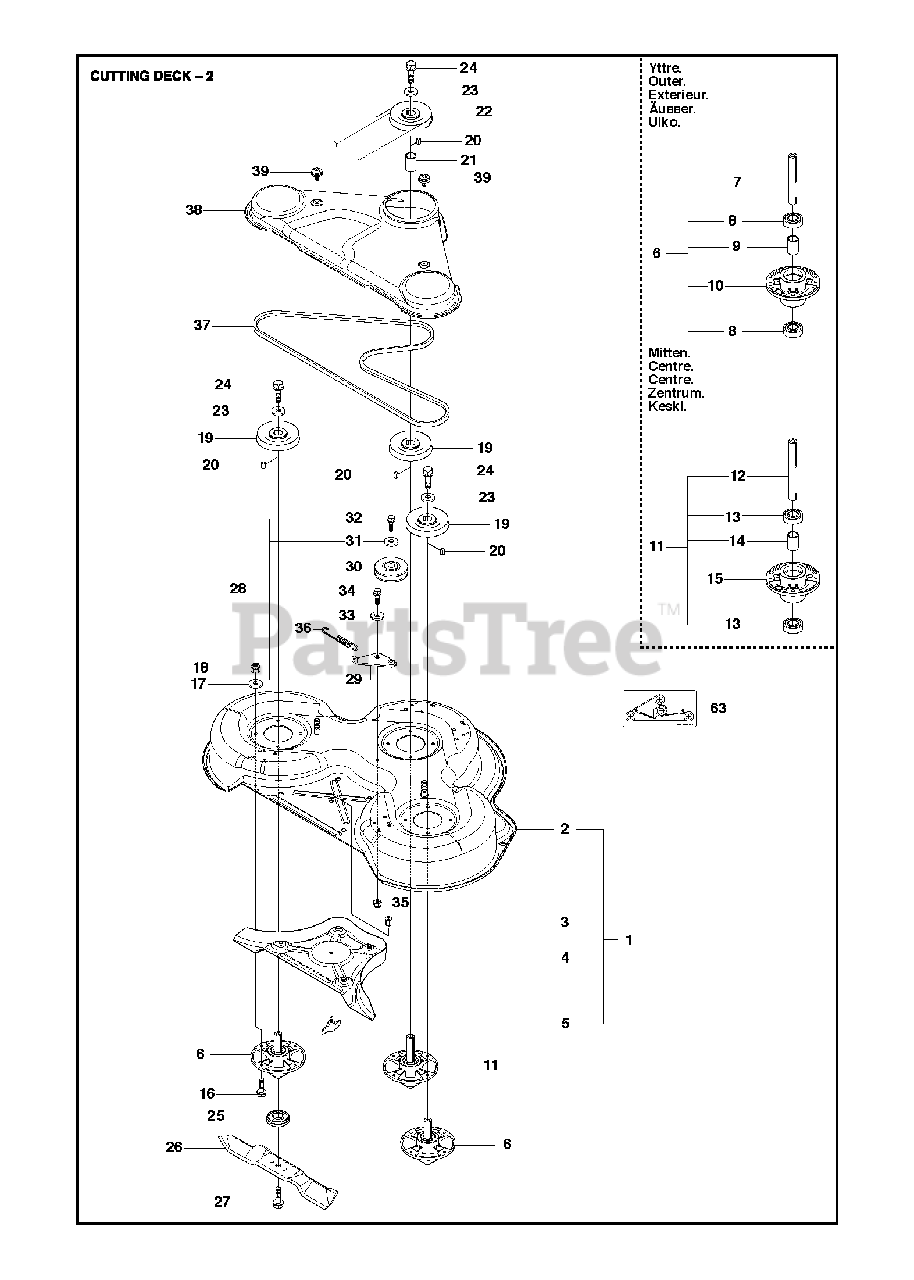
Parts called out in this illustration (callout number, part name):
3	NUT
6	BLADE HOUSING ASSY
7	SHAFT
8	BEARING
9	SPACING SLEEVE
10	BEARING HOUSING
13	BEARING
14	SPACING SLEEVE
15	BEARING HOUSING
17	WASHER BRB 8.4X17
18	LOCKNUT M8
29	BRACKET
30	PULLEY
31	SPACER
32	BOLT
33	WASHER
35	LOCKNUT M8
